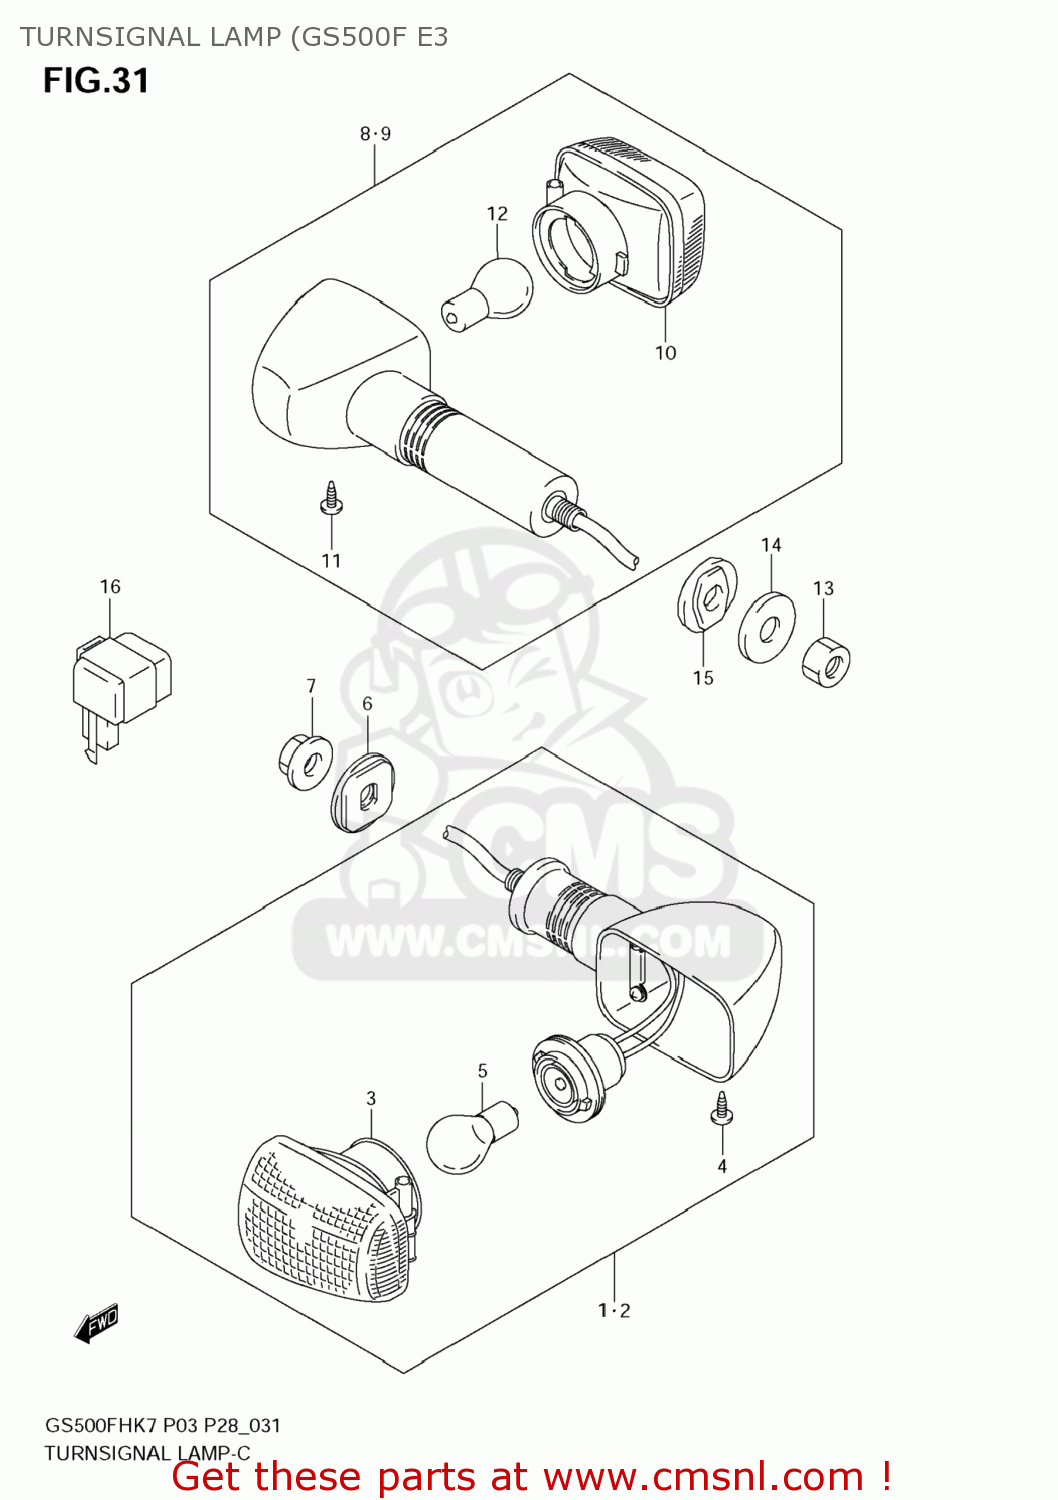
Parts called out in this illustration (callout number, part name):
1	LAMP ASSY FRON
2	LAMP ASSY FR
3	LAMP UNIT
4	SCREW
5	BULB(12V21W)
6	PLATE FR.TURNS
7	NUT
8	LAMP ASSY REAR
9	LAMP ASSY REAR
10	LAMP UNIT
11	SCREW
12	BULB(12V21W)
13	NUT
14	WASHER(10.5X30X2.3)
15	SPACER,RR TURNSIGNAL
16	RELAY ASSY, TURNSIGNAL
